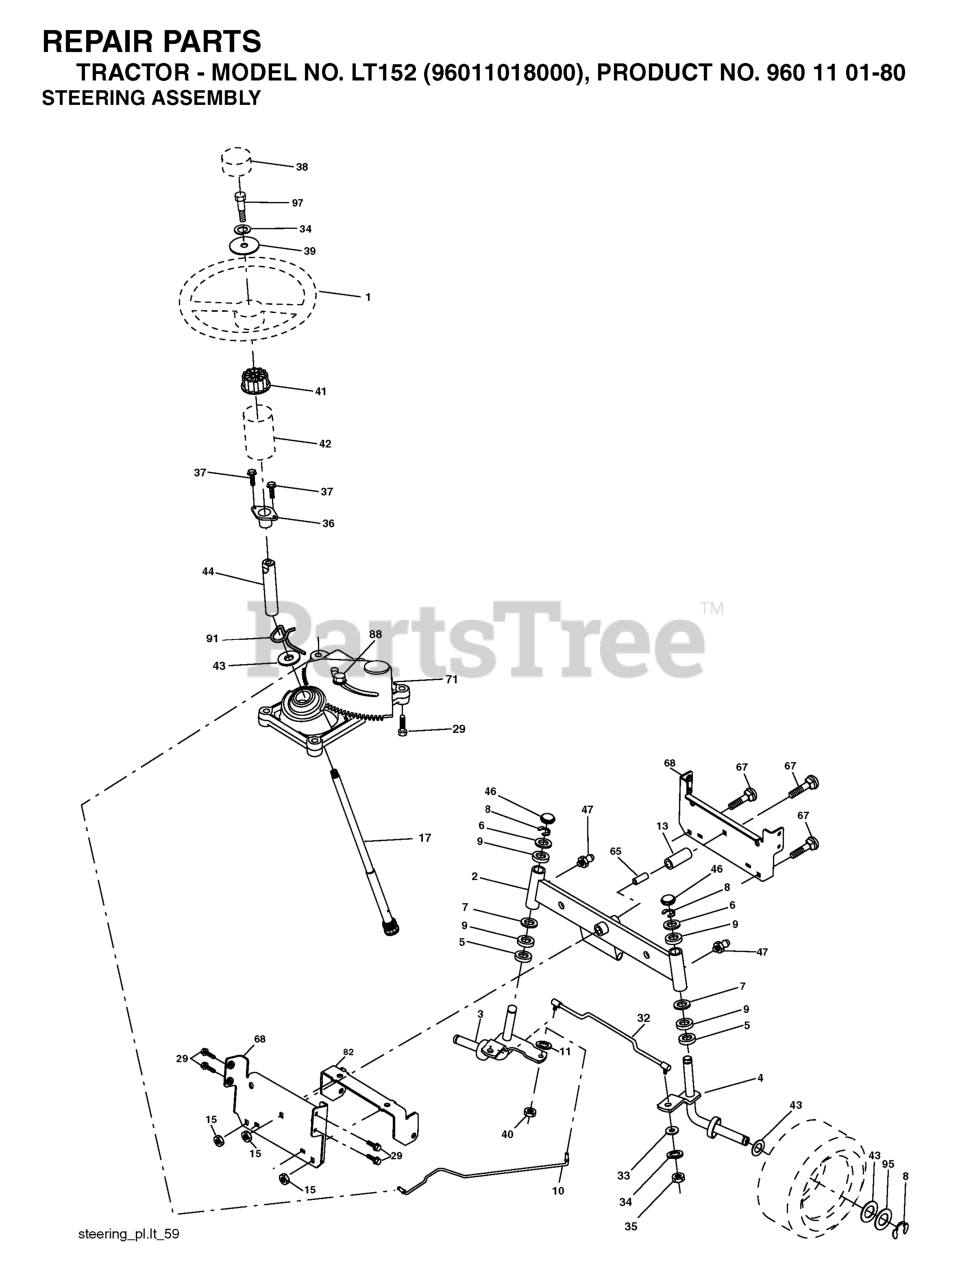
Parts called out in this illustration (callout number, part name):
1	WHEEL.STEERING.LEGEND2.GRY
2	AXLE.HALF.ASM.WELDED
3	SPINDLE.ASM.LH.15"TIRES
4	SPINDLE.ASM.RH.15"TIRES
5	THRUST WASHER
9	BRNG T
10	DRAGLINK.15".TIRES.2001
11	WASHER, LOCK 3/8
13	TUBE, PIVOT AXLE
15	NUT
17	SHAFT STEERING SPLINE
29	SCREW, 3/8-16X3/4
33	WASHER M
34	WASHER.LOCK.HVY.HLCL.SPR.5/16
35	NUT, CROWNLOCK
36	BUSHING, STEERING
37	SCREW.TT.#10-32X.5.3/8.FLANGE
38	INSERT.CAP.STRG.WH.GRAY
39	WASHER.11/32
40	NUT CROWNLOCK 3/8-24
41	ADAPTER, WHEEL STNG..
42	BOOT STEERING
44	SHAFT.EXTEN.STRG.SPLINE
46	CAP.SPINDLE.BLACK
47	FITTING.GREASE.TAPERED
65	SPACER BRACE AXLE
67	BOLT CARRIAGE
68	BRACE.AXLE.15"TIRES
71	STEERING ASM
82	BRACKET.SUSP.CHASSIS.FRONT.15
88	BOLT, SHOULDER 7/16-20
91	CLIP.STEERING
95	WASHER.HARDENED
